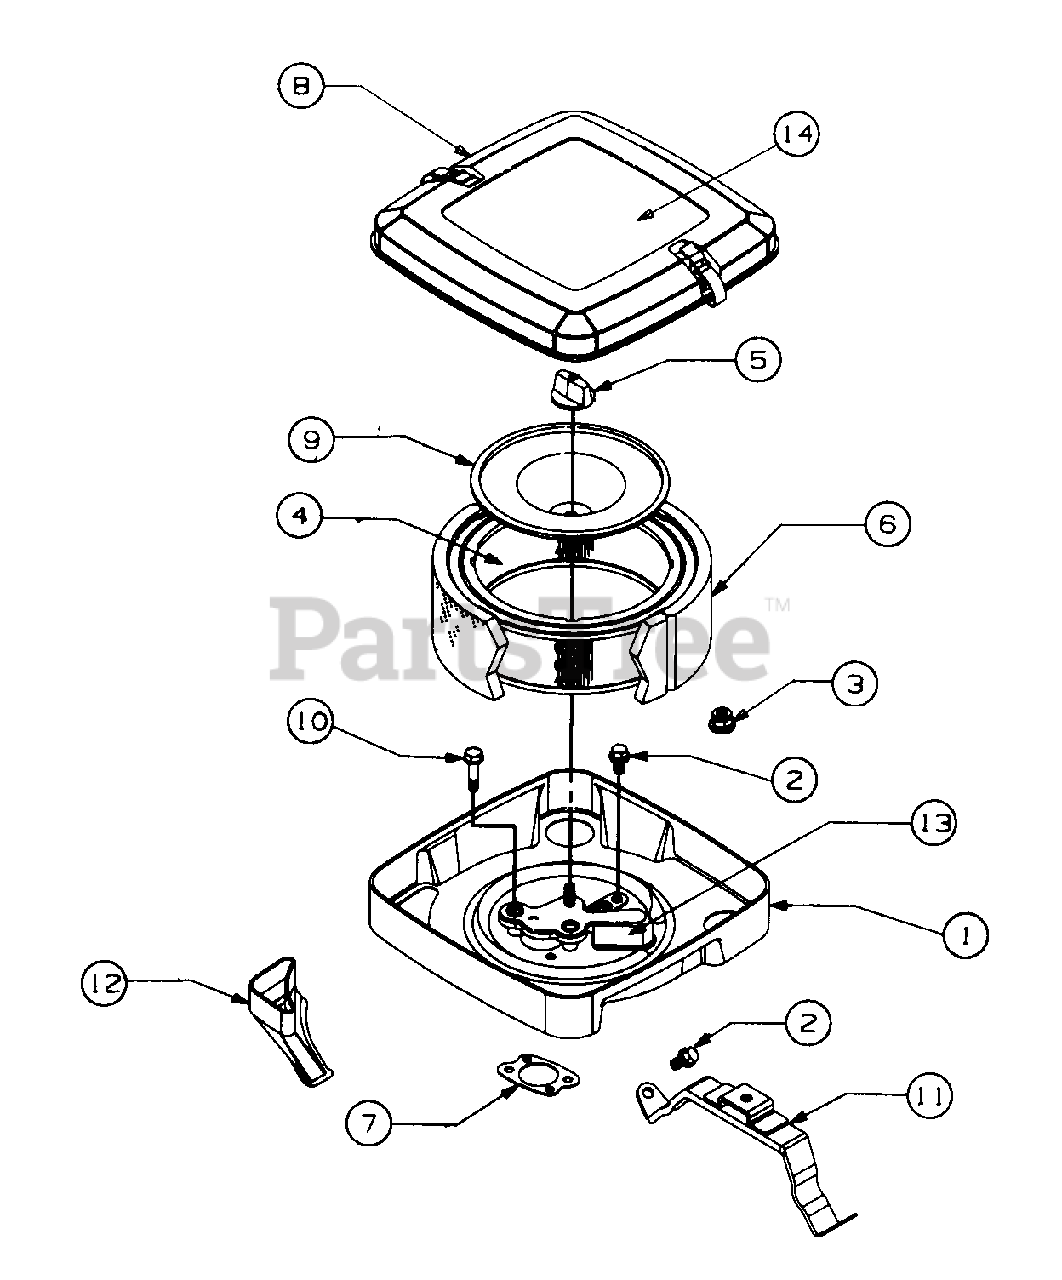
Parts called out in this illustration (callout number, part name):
1	Base Assy, Air Cleaner
2	Screw, Sem
3	Nut, Hex Washer Hd
4	Cartridge, Air Filter
5	Knob, Air Cleaner
6	Element, Pre-Cleaner
7	Gasket, Air Cleaner
8	Cover Assy, Air Cleaner
9	Plate, Air Filter
10	Screw, Sem
11	Bracket, Air Cleaner
12	Tube, Air Inlet
13	Deflector, Air Cleaner
14	Label V-Twin Engine
